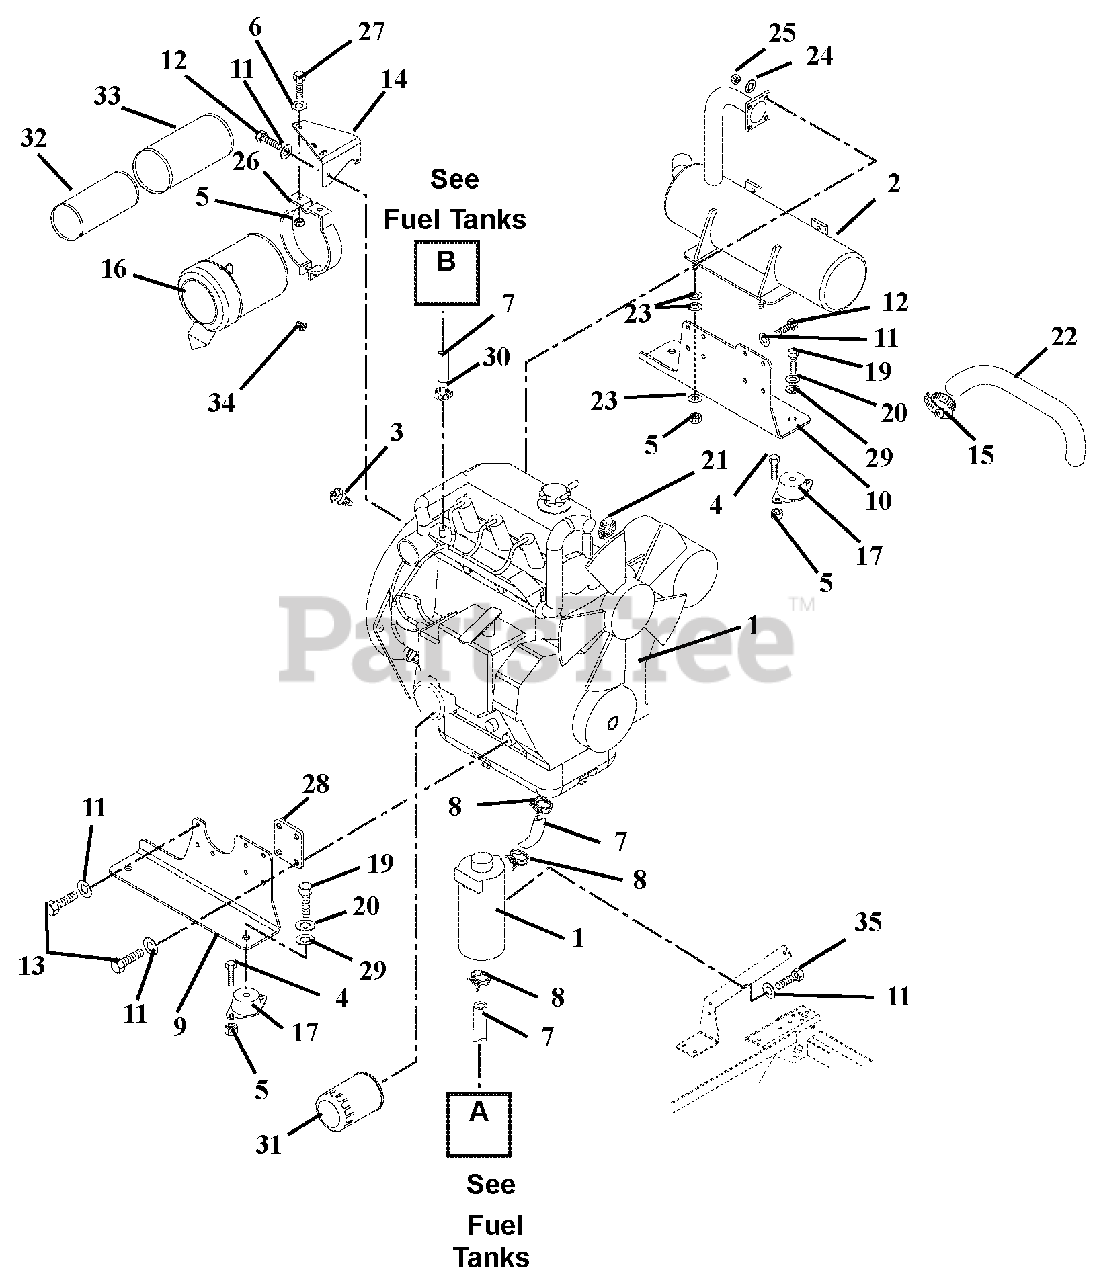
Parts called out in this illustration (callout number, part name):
1	Engine, 27HP Daihatsu Diesel (950D) (316, 322)
2	Muffler (316, 322)
3	Sender, Temperature
4	Bolt, Hex .31-18 x .75 Grade 5
5	Nut, Locking Top Flange .31-18
6	Washer, Locking .25 x .062 Regular
7	Gas Line, Bulk .31" ID
8	Hose, Clamp
9	Mount, Engine Right Hand
10	Mount, Engine Left Hand
11	Washer, Lock .31 x .078 Regular
12	Bolt, Hex M8-1.25 x 20
13	Bolt, Hex M8 x 1.25 x 25 Grade 8
14	Bracket, Air Cleaner
15	Clamp, 2.50" Dia. Hose
16	Assembly, Air Cleaner
17	Mount, Engine
18	Bolt, Hex .31-18 x 1.00 Grade 5
19	Bolt, Hex .50-20 x 1.00 Grade 5
20	Washer, Locking .50 x .125 Regular
21	Clamp, Hose 1.50 x .81 x 1.42
22	Hose, Air Cleaner (316, 322)
23	Washer, Flat Steel .38 x .875 x .083
24	Washer, Locking .31 x .078 Regular
25	Nut, Hex M8-1.25
26	Bracket, Air Cleaner Mount
27	Washer, Flat Steel .38 x .875 x .083
28	Spacer, Engine Mounting
29	Washer, Flat Steel .531 x 1.06 x .095
30	Hose Clamp
31	Oil Filter
32	Element, Inner Safety
33	Element, Outer Primary
34	Plug, Pipe .125-27
35	Bolt, Hex M6-1 x 16
